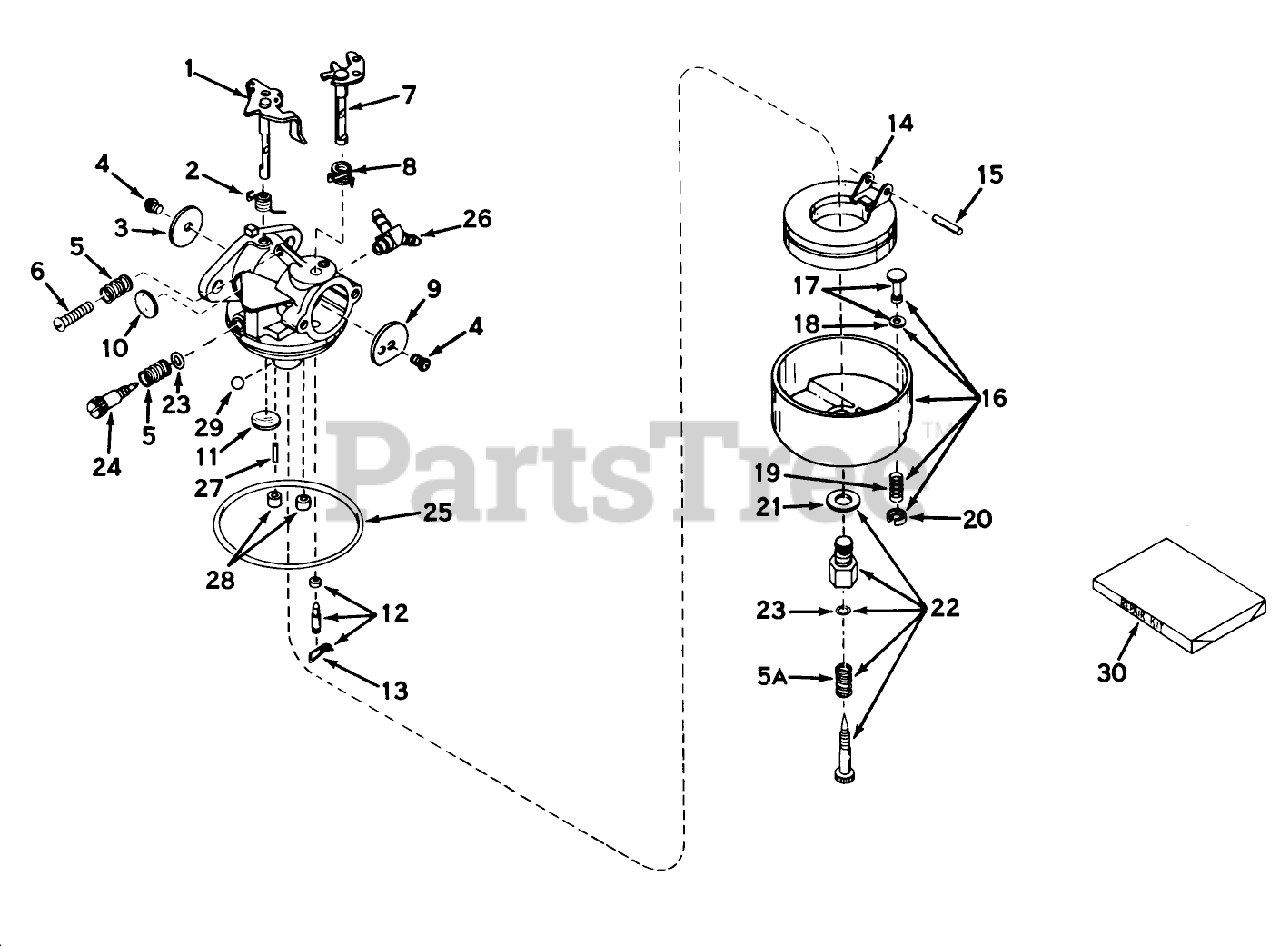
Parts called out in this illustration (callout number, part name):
1	Shaft/Lever-Throttle
2	Spring, Return
3	Shutter-Throttle
4	Screw-Shutter
5	Spring-Tension
5A	Spring
6	Screw-Throttle Crack Screw / Idle Speed
7	Shaft Lever Assy., Choke
8	Spring, Choke return
9	Shutter-Choke
10	Plug-Welch, Idle Mixture Well
11	Plug-Welch, Atmospheric Vent
12	Inlet Needle, Seat Clip Assy. (Incl. No. 13)
13	Clip-Spring
14	Float,Carburetor
15	Shaft-Float
16	Bowl Drain Assy., Float (Incl. No. 17)
17	Plunger Assy., Drain (Incl. Ref. 18)
18	Gasket-Plunger, Drain
19	Spring, Drain Plunger
20	Retainer, Plunger Spring
21	Washer-Bowl Nut
22	Adjustment Screw Assy., Main (Incl. Nos. 5A, 21 23)
23	ORing
24	Screw, Idle Adj.
25	O Ring-Bowl, Float
26	Fitting, Fuel inlet
28	Plug, Cup
29	BalI, Steel
30	Repair Kit
